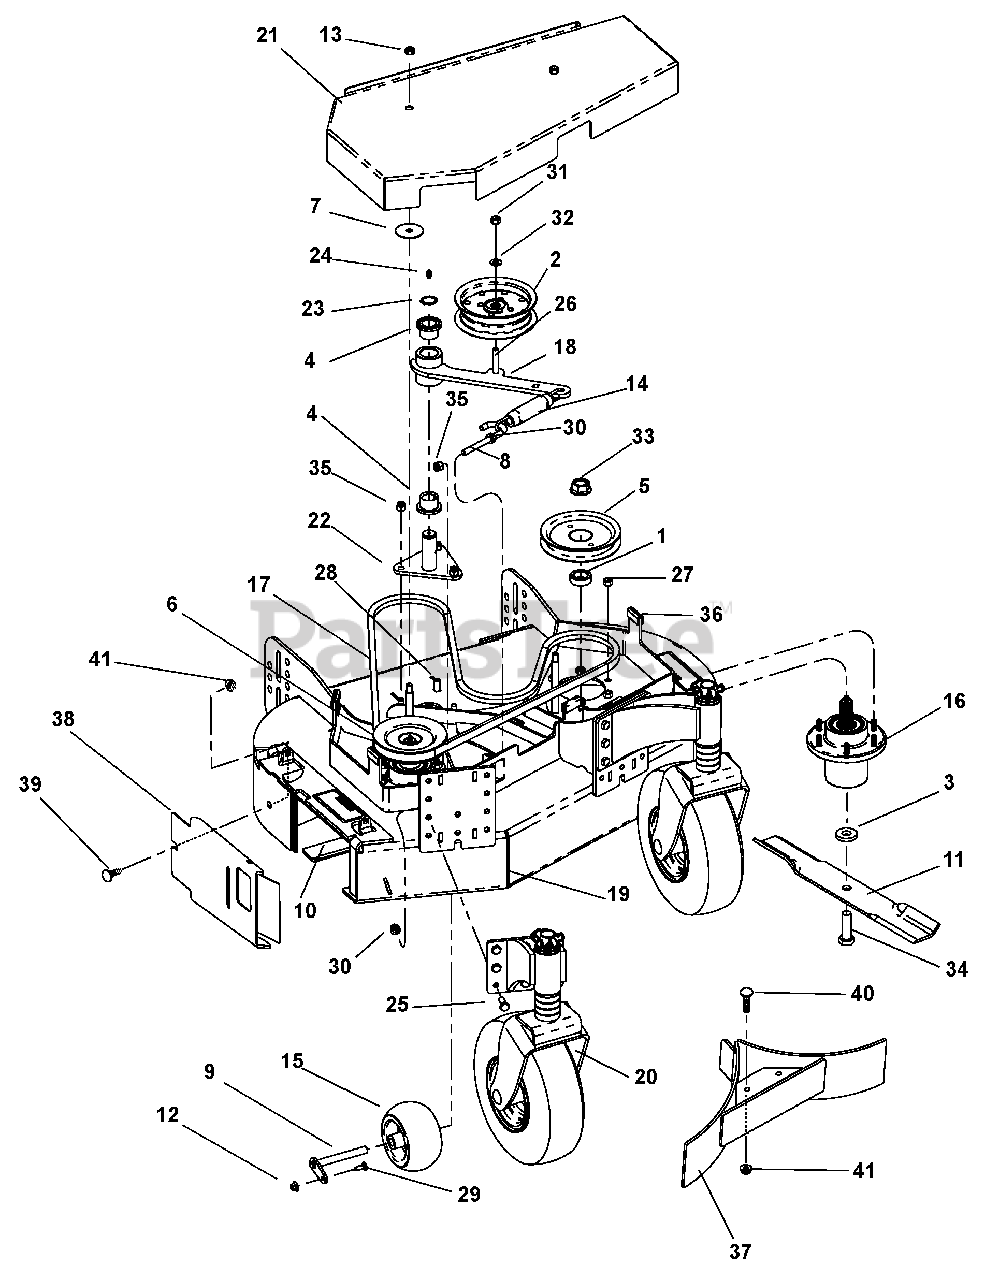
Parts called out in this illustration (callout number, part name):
1	SPACER, PULLEY
2	PULLEY, FLAT TENSION IDLER
3	SPACER, BLADE BOLT
4	BALL BEARING
5	PULLEY, CUTTER HOUSING 52" DEC
6	PULLEY, CUTTER HOUSING 48" DEC
7	WSHR-FL-STL .402X2.00X.055 YWZ
8	J-HOOK
9	PIVOT, ANTI-SCALP ROLLER
10	BLADE-MOWER 16.50" LOW-LIFT
11	BLADE-MOWER 18.00" LOW-LIFT
12	NUT-1/4" FLANGE PREVAILING TOR
13	@NUT-LK-TOP-FLG .38-16 YWZC
14	SPRING, DECK BELT TENSION
15	WHEEL, GAGE, 48" AND 52" DECK
16	SPINDLE ASSEMBLY, INCLUDES ITE
17	BELT, HB 80.3 EL AMD OHR
18	WLDT, IDLER ARM
19	WLDT, 34" DECK
20	ASSY, FR WHEEL CASTER
21	SHIELD, DECK 34
22	WLDT, IDLER PIVOT
23	SNAP RING, 1.00 X .042 EXT
24	FTG, 1/4-28 STRGT GREASE ZERK
25	BOLT, 3/8-16X1.00 HEX 5 Y
26	BOLT, 3/8-16X2.25 HEX 5 Y
27	NUT, 3/8-16 STD HEX GR5 Y
28	BOLT, 3/8-16X1.00 CRG 5 SN Y
29	BOLT, 1/4-20X.750 CRG 5 Y
30	LOCKNUT, 3/8-16 WHIZ Y
31	LOCKNUT, 3/8-16 CROWN Y
32	WASHER, .406X.813X.065 FLAT Y
33	NUT, 3/4-16 FLANGE GR8 Y
34	BOLT, 5/8-11 X 2.00 HEX 8 Y
35	LOCKNUT, 3/8-16 NYLOC Y
36	TRIM, LOCK 1/4" EDGE
37	WLDT, BAFFLE
38	WLDT, BAFFLE AND END PLATE
39	BOLT, 3/8-16X1.25 CRG 5 Y
40	BOLT, 3/8-16X1.00 HEX 5 Y
41	LOCKNUT, 3/8-16 NYLOC Y
